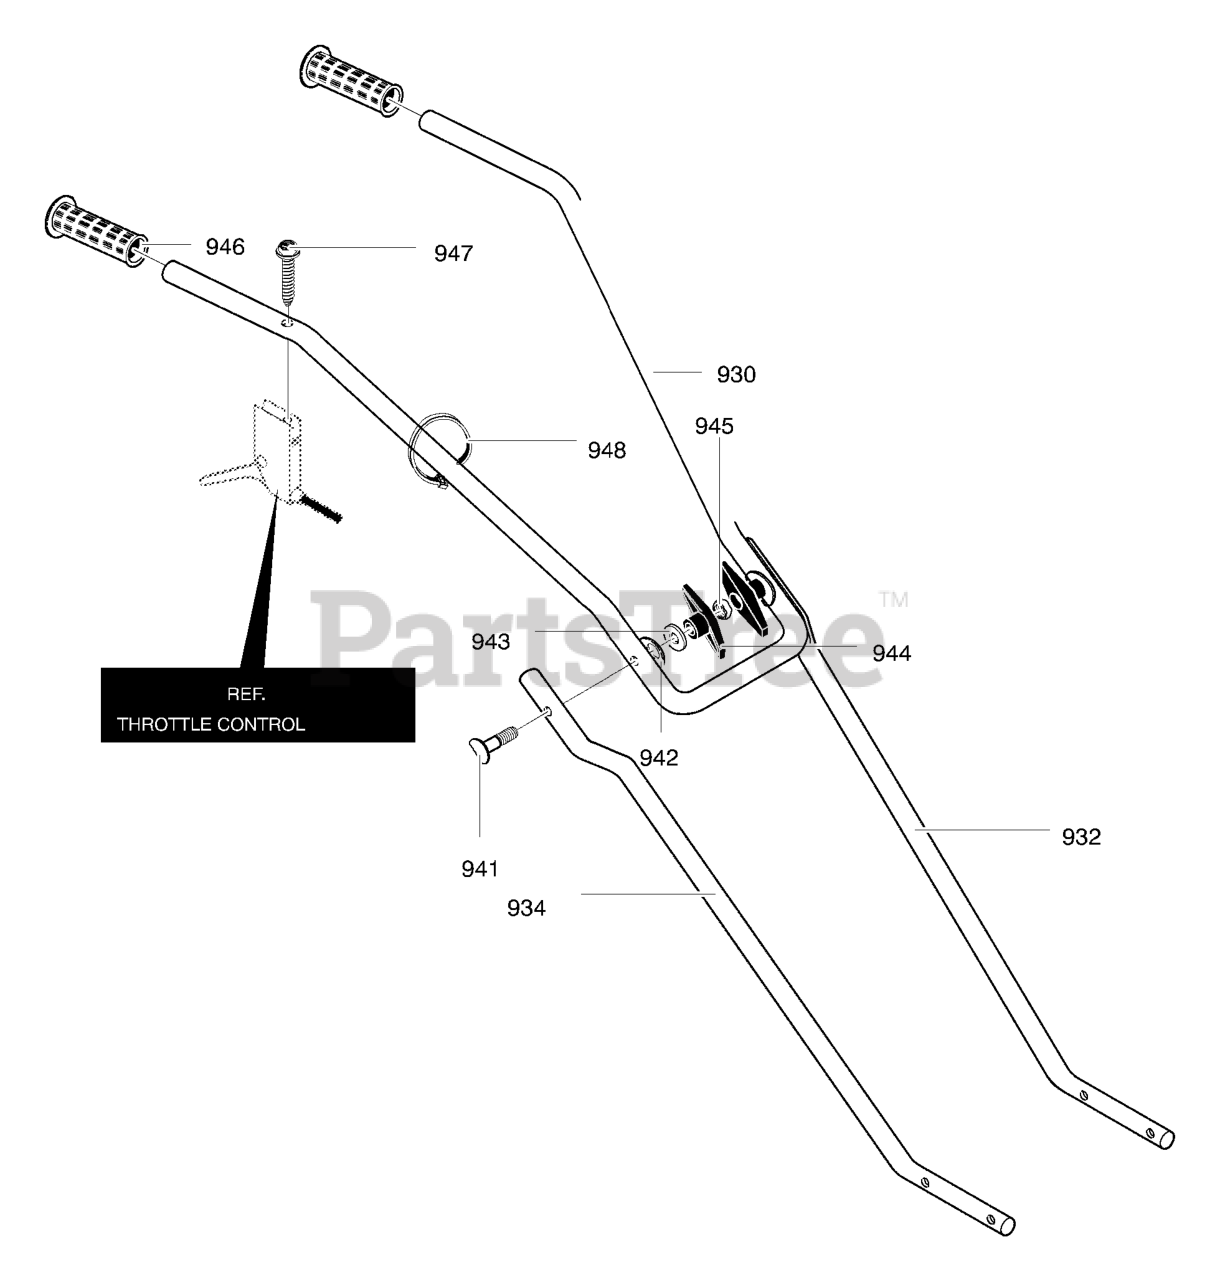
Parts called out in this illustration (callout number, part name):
930	Upper Handle
932	Lower Handle LH
934	Lower Handle RH
941	Bolt 5/16-18x1.63
942	Formed Washer
943	Flat washer
944	T Knob
945	Nut, 5/16-18
946	Hand Grip
